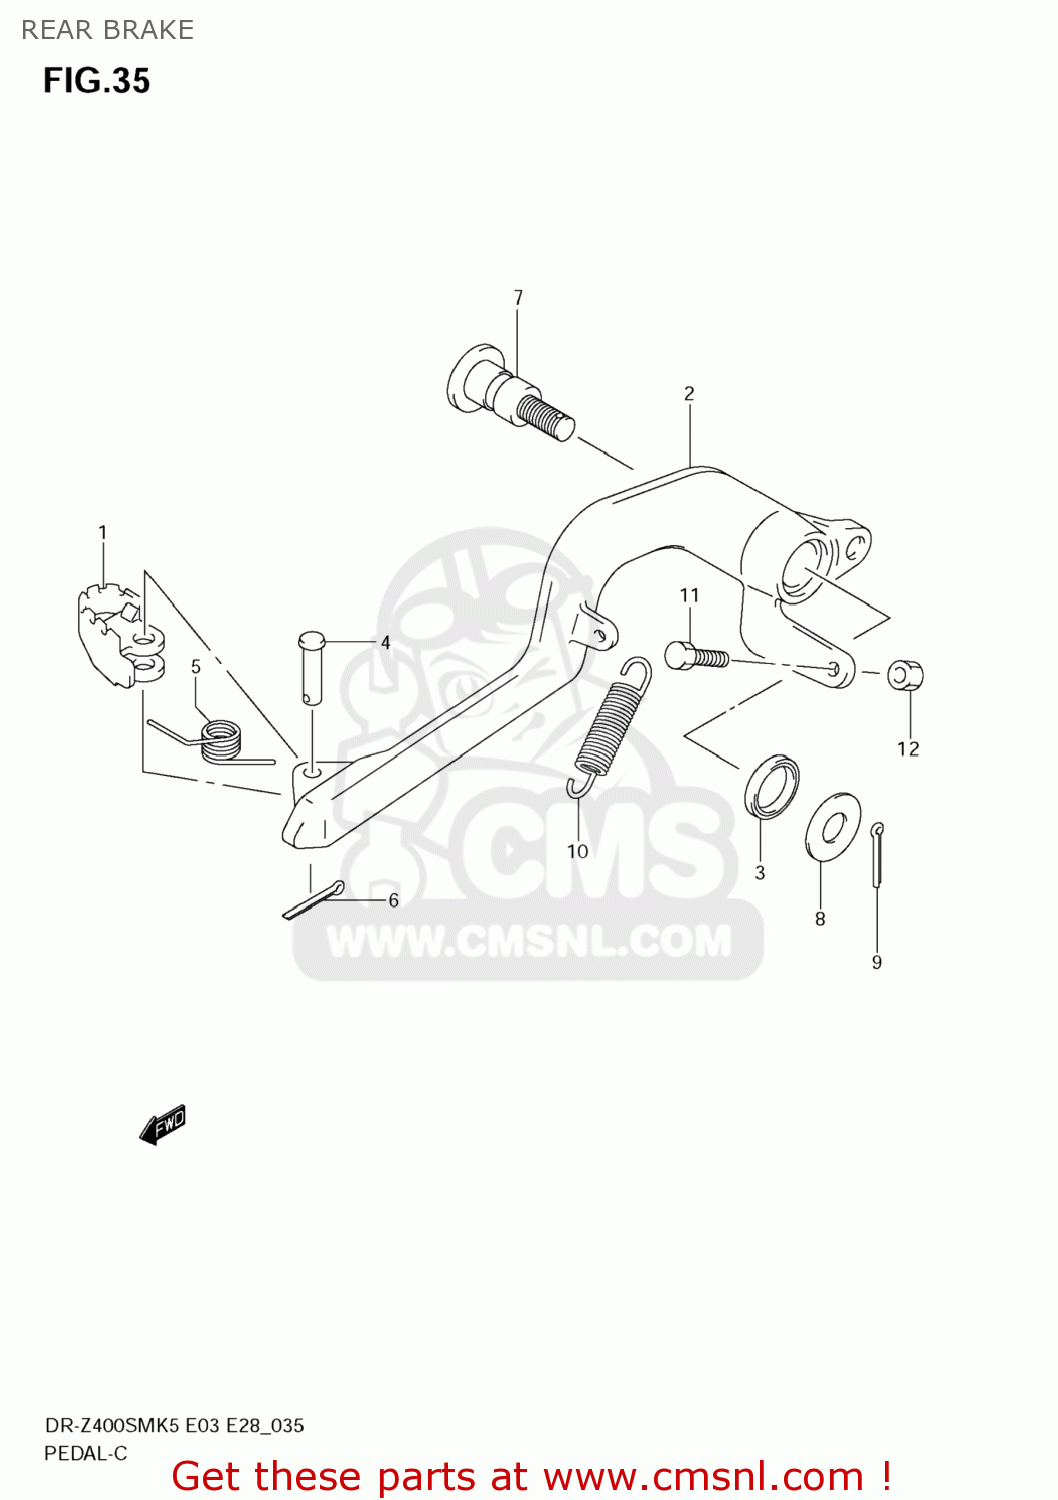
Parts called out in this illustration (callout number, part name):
1	PEDAL,BRAKE
2	ARM,BRAKE PEDAL
3	SEAL,OIL(15X21X3)
4	PIN(6X23.5)
5	SPRING
6	PIN
7	SHAFT,BRAKE PEDAL
8	WASHER
9	PIN
10	SPRING
11	BOLT(6X30)
12	NUT
